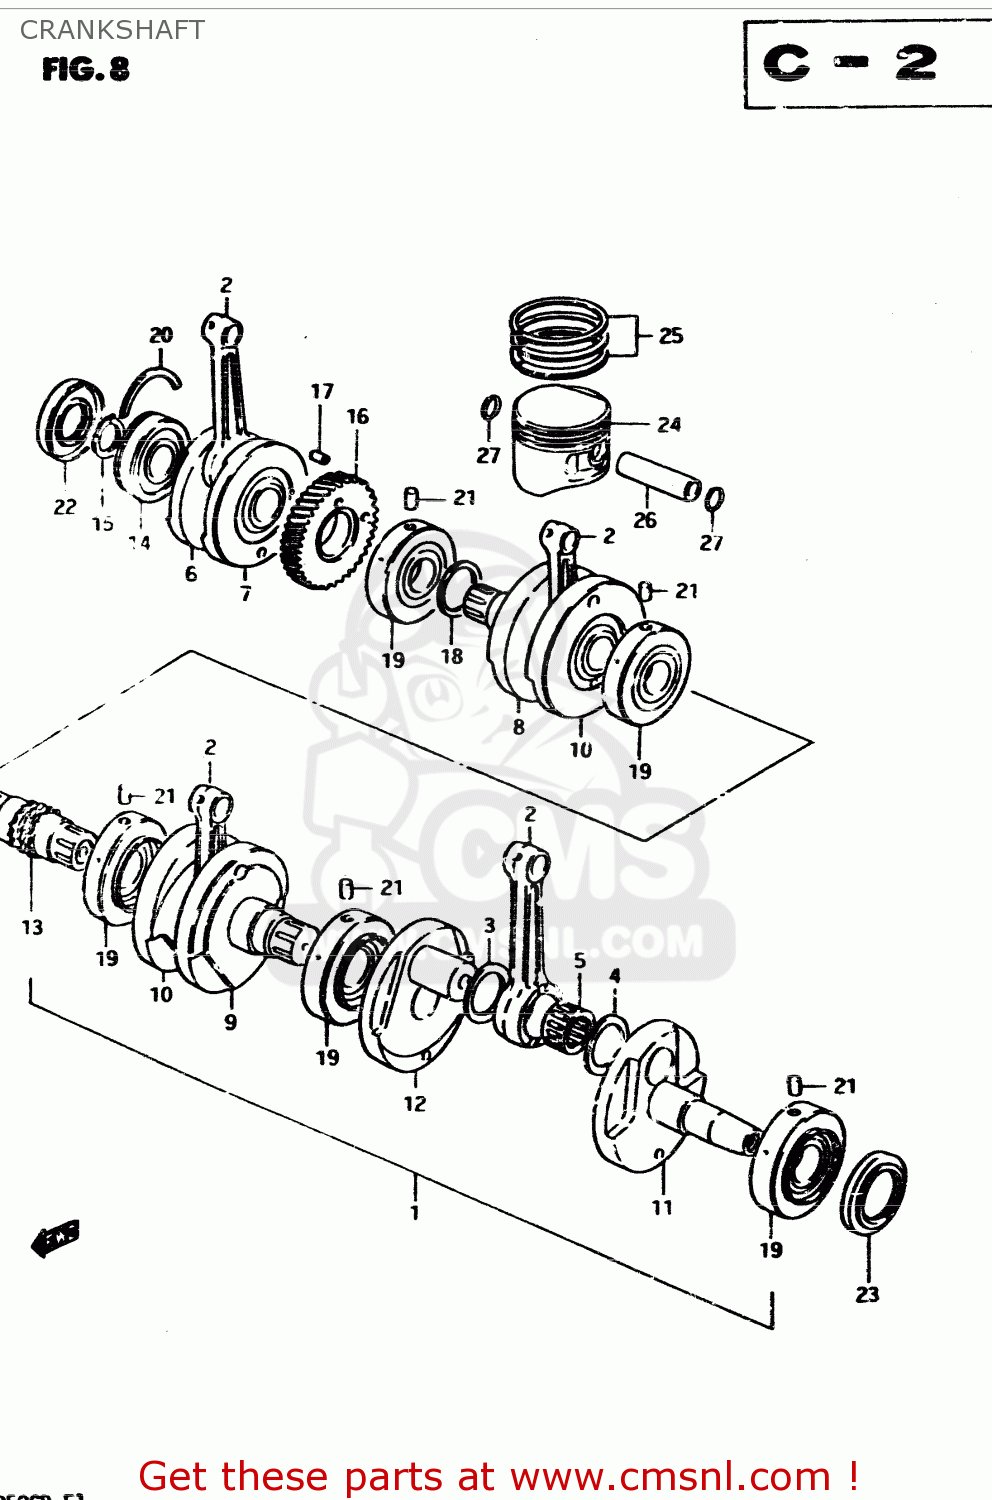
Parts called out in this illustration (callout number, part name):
1	CRANKSHAFT ASSEMBLY
2	ROD,CONNECTING
3	WASHER (29X48X2)
4	WASHER (29X48X1)
5	BEARING(29X39X20)
6	CRANKSHAFT
7	WEB,CRANK,RIGHT
8	CRANKSHAFT
9	CRANKSHAFT, MIDDLE LH
10	WEB,CRANK,MIDDLE
11	CRANKSHAFT,LEFT
12	WEB,CRANK,LEFT
13	SHAFT,TIMING CHAIN DRIVE
14	BEARING(30X72X19)
15	CIRCLIP,30MM
16	GEAR,PRIMARY DRIVE
17	PIN
18	WASHER
19	BEARING
20	C RING
21	PIN
22	SEAL,OIL(30X72X11)
23	OIL SEAL
24	PISTON
25	RING SET,PISTON
26	PIN,PISTON
27	CIRCLIP
